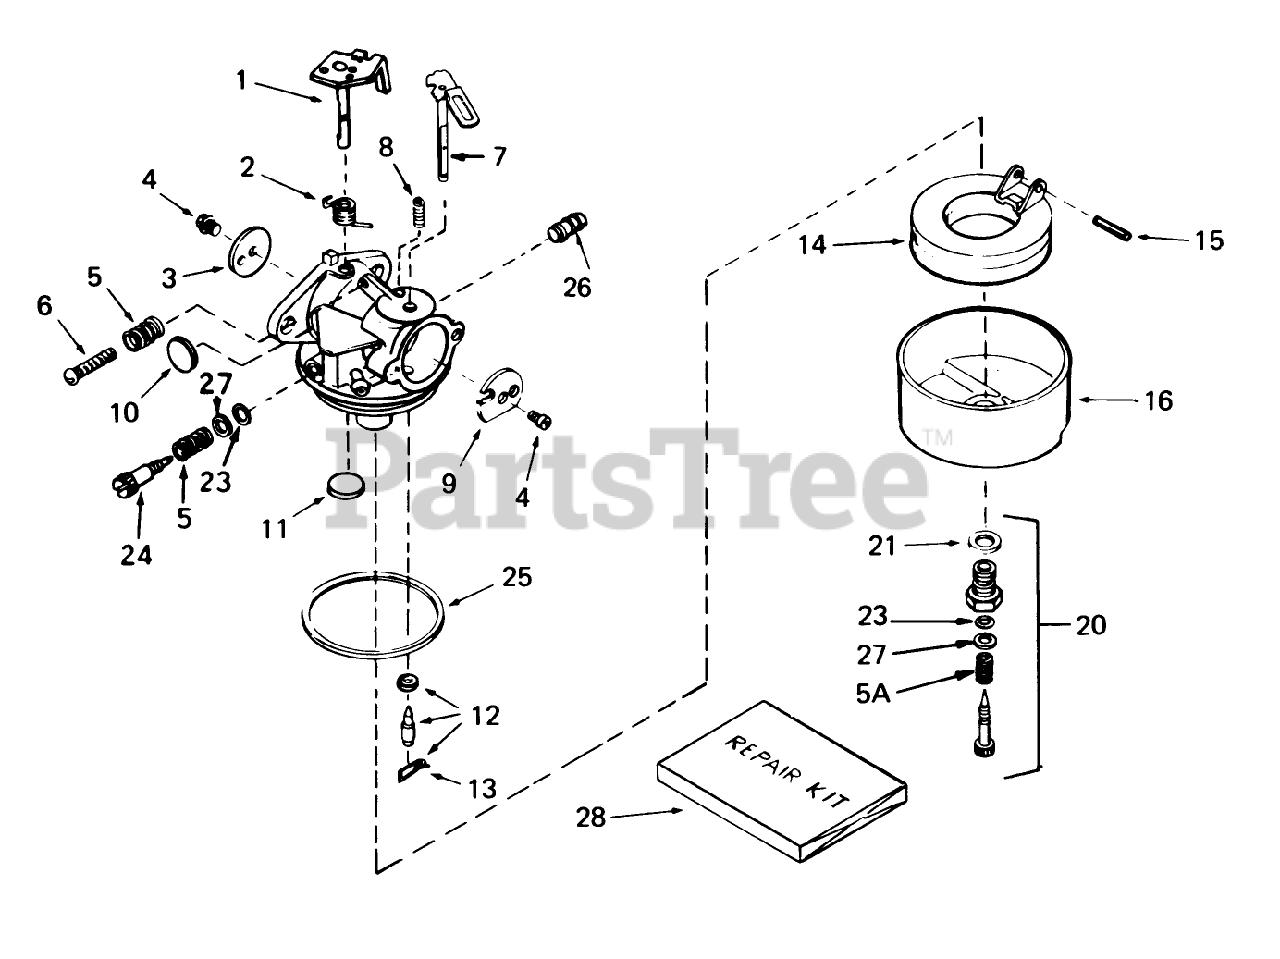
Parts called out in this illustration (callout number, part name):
1	Shaft/Lever-Throttle
2	Spring-Return, Throttle
3	Shutter-Throttle
4	Screw-Shutter
5	Spring-Tension
5A	Spring
6	Screw-Throttle Crack Screw / Idle Speed
7	Choke Shaft and Lever ASM
8	Spring-Positioning, Choke
9	Shutter-Choke
10	Plug-Welch, Idle Mixture Well
11	Plug-Welch, Atmospheric Vent
12	Inlet Needle, Seat Clip Assy. (Incl. No. 13)
13	Clip-Spring
14	Float
15	Shaft-Float
16	Bowl-Float (no drain)
20	Adjustment Screw Assy.,Main (Incl. Ref. #5A,21,23 30)
21	Washer-Bowl Nut
23	ORing
24	Screw Main Adjustment
25	O Ring-Bowl, Float
26	Fitting-Fuel
27	Washer
28	Repair Kit
